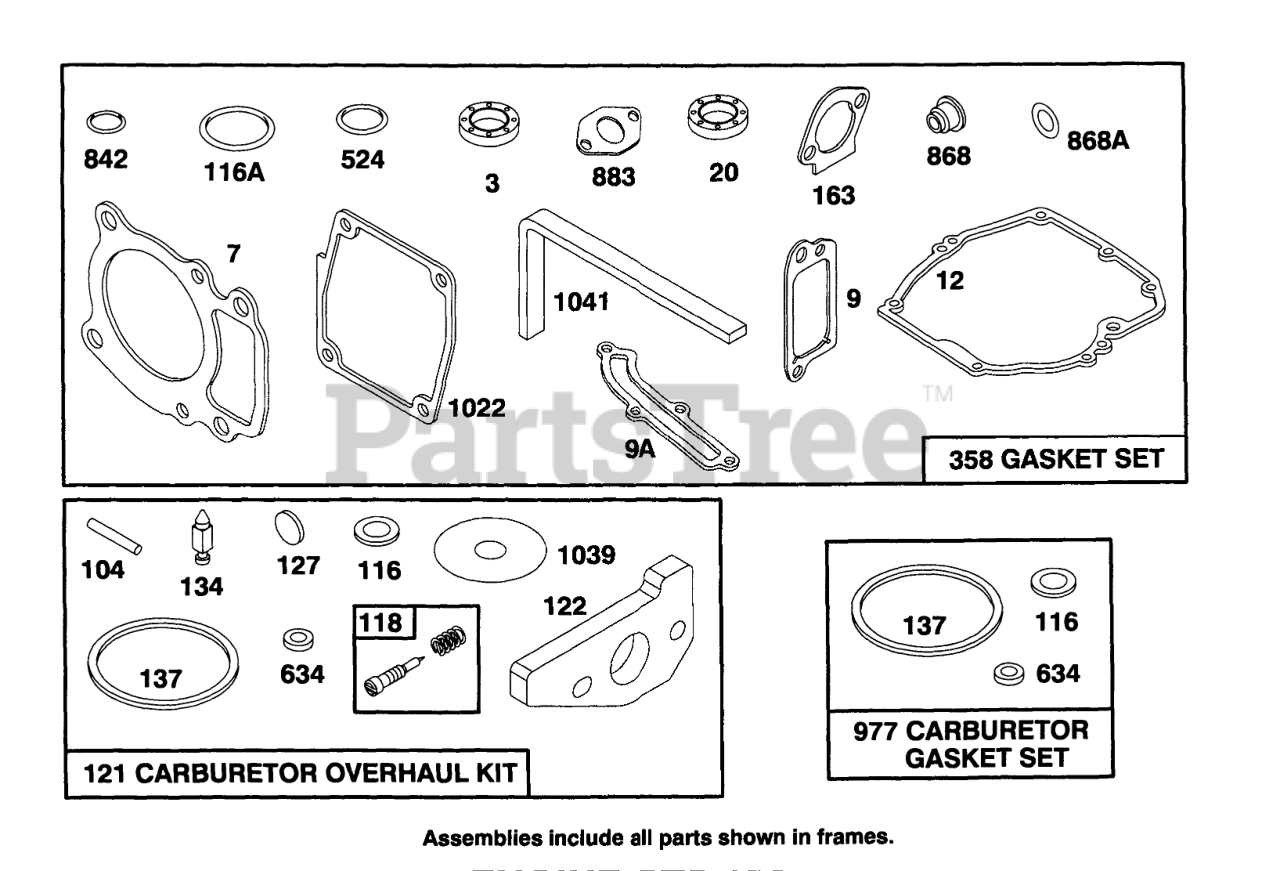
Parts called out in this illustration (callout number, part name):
3	SEAL - OIL
7	CYLINDER HEAD GASKET
8	BREATHER GASKET
9A	GASKET-BREATHER
12	ENGINE BASE GASKET
20	SEAL-OIL
104	FLOAT HINGE PIN
116	SEALING GASKET
116	O-Ring
116A	O RING SEAL
118	VALVE KIT - NEEDLE
121	CARBURATOR OVERHAUL KIT
122	ADAPTER ASSEMBLY
127	PLUG
134	Valve-Inlet (Includes Seat)
137	FLOAT BOWL GASKET
163	AIR CLEANER GASKET
358	GASKET SET
524	O-RING
634	SEAL WASHER
842	O-RING
868	SealAssy-Valve
868A	Seal-Valve
883	EXHAUST GASKET
977	CARBURATOR GASKET SET
1022	ROCKER COVER GASKET
1039	FLOAT LIMITER
1041	SEAL - FOAM
